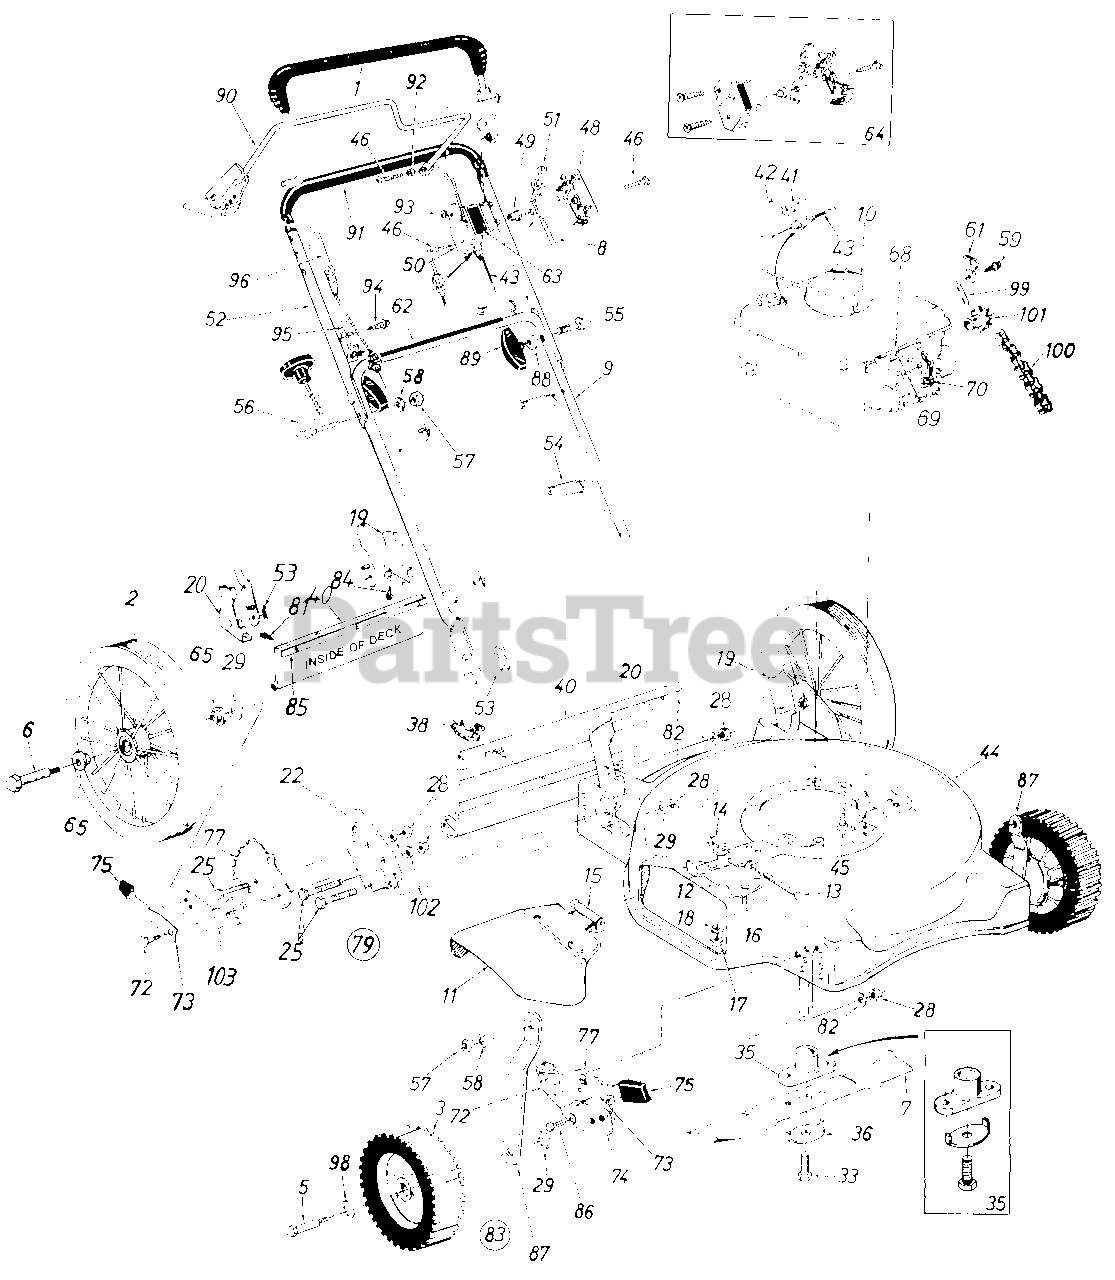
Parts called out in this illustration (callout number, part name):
1	Control Handle Ass'y.
2	Rear Wheel Ass'y.-Comp. 14.0x 1.75
3	Front Wheel Ass'y.-Comp. 8.0x 1.75
5	Front Axle Bolt
6	Rear Axle Bolt
7	22" Blade
8	Throttle Wire-53" Lg.
9	Lower Handle
11	Chute Deflector Ass'y. Comp.
12	IAdapter Plate
13	Pivot Pin
14	Push Nut 1/4" Rod
15	Torsion Spring
16	Hex Bolt 1/4-20 x .50" Lg.
17	Hex Nut 1/4-20 Thd.*
18	L-Wash. 1/4" I.D.
19	Handle Mount Brkt.-L.H.
20	Handle Mount Brkt.-R.H.
22	Mounting Plate
25	Hex Bolt 3/8-16 x .75" Lg.
28	Hex Nut 3/8-16 Thd.
29	Bell-Wash. .400" I.D. x .88"
33	Hex Bolt 3/8-24 x 1.5" Lg. (Grade 5)
35	Blade Adapter Kit
36	Blade Bell-Wash.
38	Hinge Clip
40	Rear Flap Ass y.
41	Cable Bracket
42	Pop Rivet .156 Dia. x .379
43	Control Cable-39"
44	22" Deck Assy.
45	Hex Wash. Hd. TT-Tap Scr. 3/8-16 x 1.00" Lg.
46	Truss Mach. "B"-Tap Scr. #12 x 1.50" Lg.
48	Control Panel Half
49	Control Disc Pin
50	Clutch Panel Half
51	Throttle Control Lever
52	Upper Handle
53	Intern. Cot. Pin 5/16" Dia.
54	Cable Tie
55	Curved Carriage Bolt 5/16-18 x 1.75" Lg.
56	Rope Guide Bolt
57	Hex Nut 5/16-18 Thd.
58	L-Wash. 5/16" I.D.
59	Hex B-Tap Scr. #10 x .38" Lg.
61	Casing Clamp
62	Instruction Label-Handle
63	Control Label-Throttle
64	Control Housing Comp.
65	Flange Bearing
68	Casing Clamp
69	Hex B-Tap Scr. #10 x .62" Lg.
70	Spark Plug Boot
72	Shoulder Bolt .50" Dia.
73	Spring Lever
74	Pivot Bar
75	Spring Lever Knob
77	Index Plate
79	Rear Height Adj. Ass'y. Comp.-R.H.
81	Hex AB-Tap Scr. 1/4 x .62" Lg.
82	Bell-Wash. .39" I.D. x 1.38"
84	Hex Self-Tap Scr. 5/16-18 x.5" Lg.
85	Retainer Stript
86	Hex Hd. AB-Tap Scr. 1/4 x .62" Lg.
87	Link
88	Bell-Wash. 5/16" I.D.
89	Hand Knob
90	S.P. Bail Ass'y.
92	Spacer .23" I.D. x .3" O.D.
93	Spr.-Wash. .206" I.D.
94	Hex Wash. AB-Tap Scr. 5/16 x.75" Lg.
95	Cable Mounting Brkt.
96	Drive Cable
98	Fl-Wash. .531" I.D. x .931'
99	Spring Pin 3/16" Dia.
100	#48 Chain 1/2" Pitch 50 Links (Endless)
101	10 Tooth Sprocket Ass'y.
102	L-Wash. 3/8" I.D.
103	Pivot Bar
